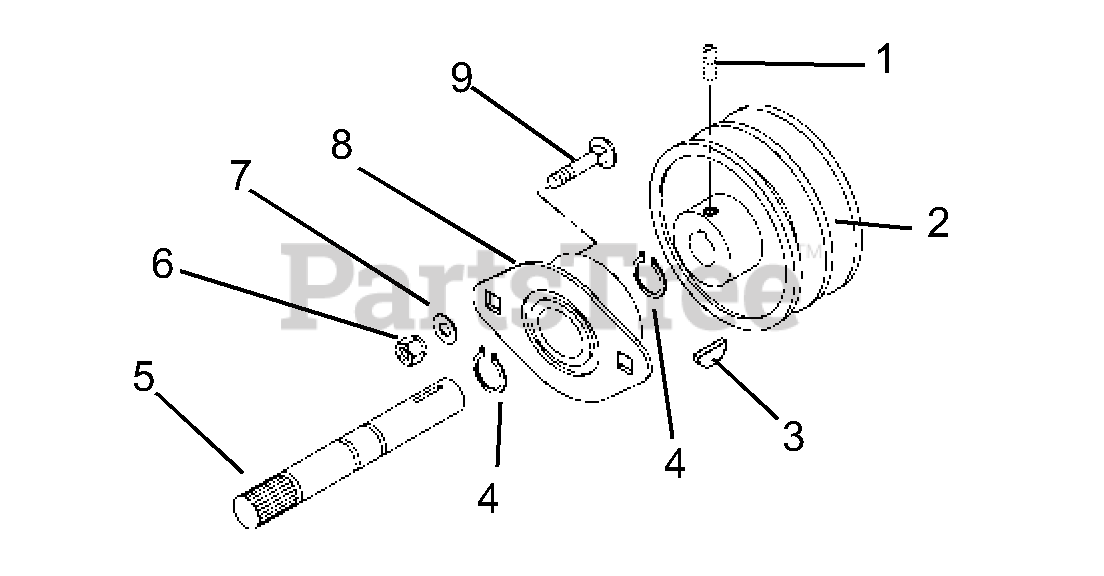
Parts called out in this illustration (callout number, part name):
1	Set Screw
2	Sheave, Drive
3	Key-Woodruff
4	Ring, Retaining-External
5	Shaft, Half
6	Nut-Locking-Nylon .25-20
7	Washer-Flat-Steel
8	Bearing-Flange
9	Bolt-Round Head Square Neck
